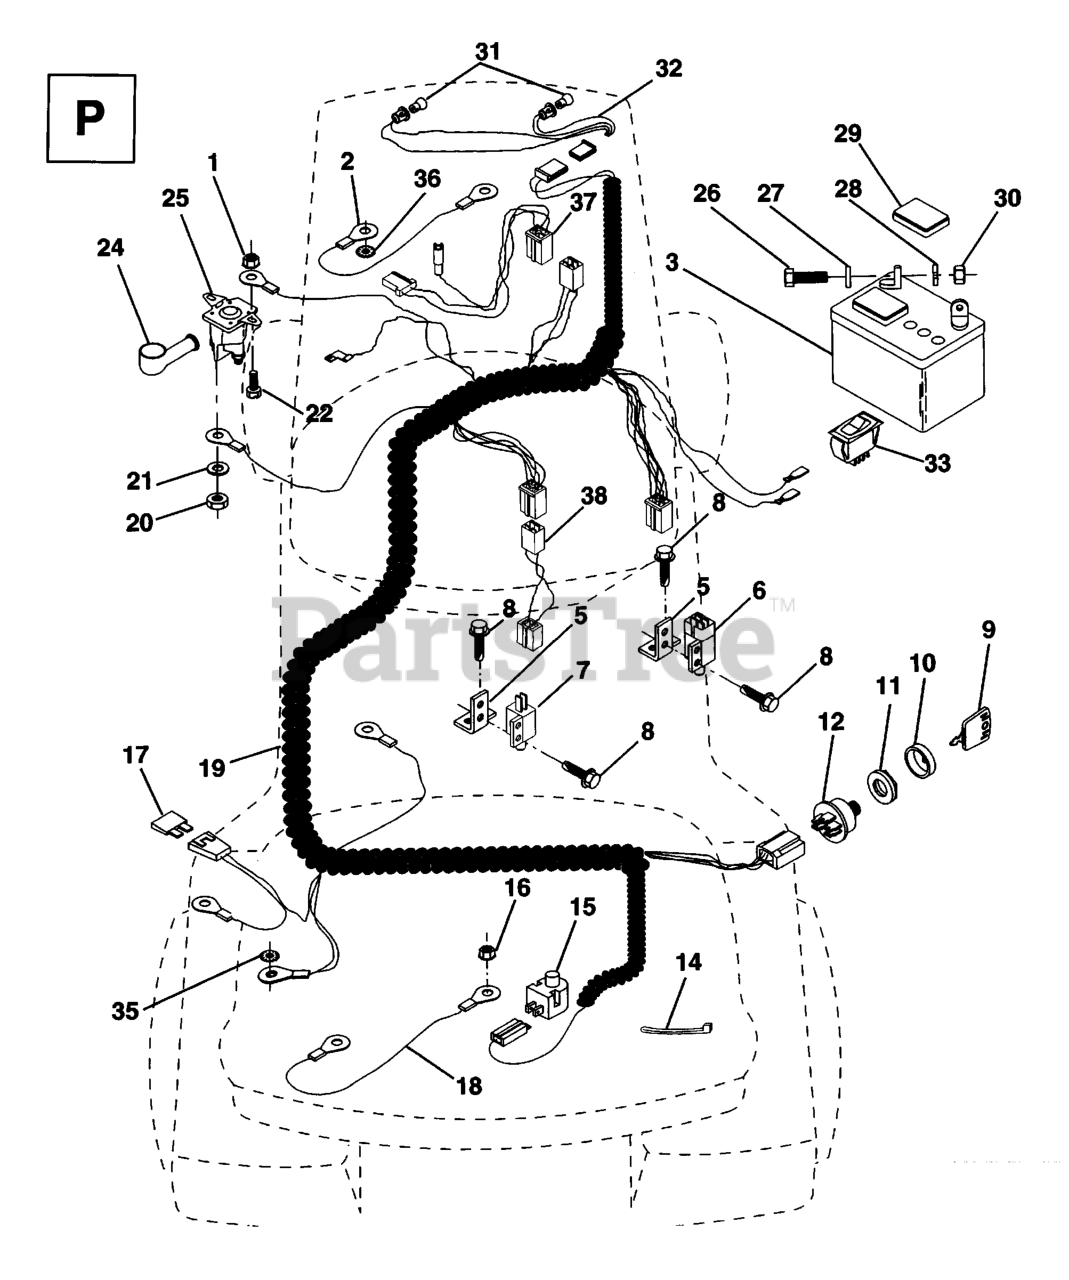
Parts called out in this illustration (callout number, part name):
1	NUT
2	CABLE.BATTERY.6GA.16"RED
3	BATTERY
5	BRACKET LT
6	SWITCH INTERLOCKT
7	SWITCH-INTER. GT
9	KEY MLD GEN DELTA
10	COVER KEY IGNITIO
11	NUT, IGNITION
12	IGNITION SWITCH
14	TIE GUIDE
15	RP.SWITCH.PLUNGER.NC.GRAY
16	NUT
18	CABLE ASSY
19	HARNESS, IGNITON
20	NUT
21	LOCKWASHER
22	BOLT
24	TERMINAL COVER
25	SOLENOID
26	BOLT.HEX.1/4.X.3/4.DICHROMATE
28	LOCKWASHER
29	CAP BATTERY NLA
30	NUT
32	SOCKET LIGHT HARNESS
35	LOCKWASHER
36	LOCKWASHER
37	HARNESS, ENGINE
38	ADAPTOR, HARNESS
